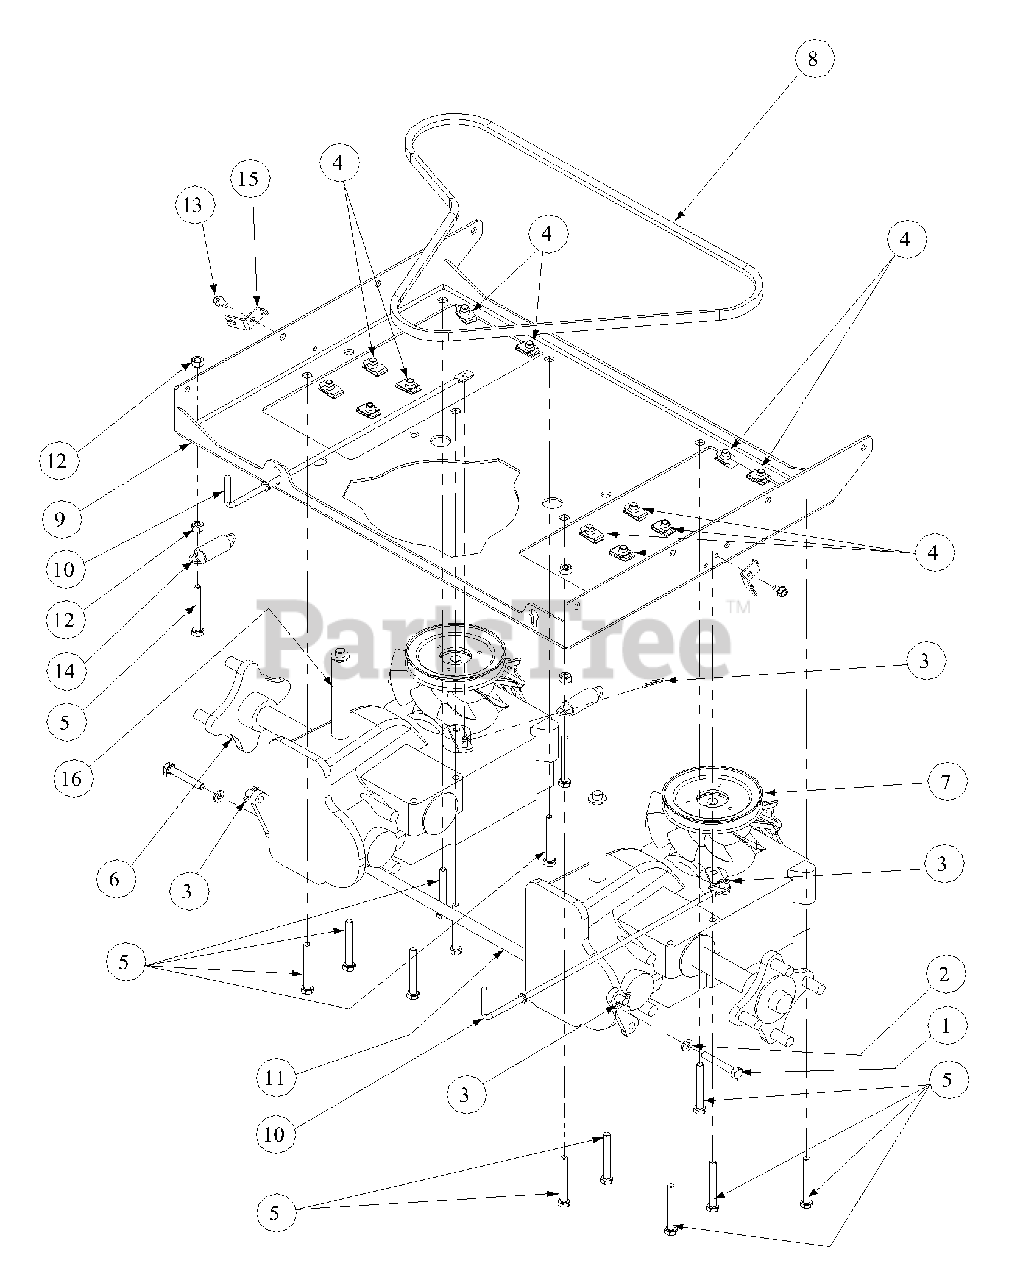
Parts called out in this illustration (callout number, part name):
1	Hex Cap Screw, 5/16-18 x 2.0
2	Flat Washer, .320 ID x .591 OD
3	Cotter Pin, .072 x 1.12 Lg
4	U-Nut, 5/16-18
5	Hex Cap Screw, 5/16-18 x 2.5
6	IZT Transmission, Left Hand
7	IZT Transmission, Right Hand
8	V-Belt, 56.00
9	Transmission Mounting Bracket
11	Transmission Brace Tube
12	Nut, 5/16-18
13	Screw, 1/4-20 x 1/2
14	Extension Spring, .438 OD x 2.50
15	Brake Cable Mounting Bracket
16	Hose, 1/2 Dia. x 4" Long
